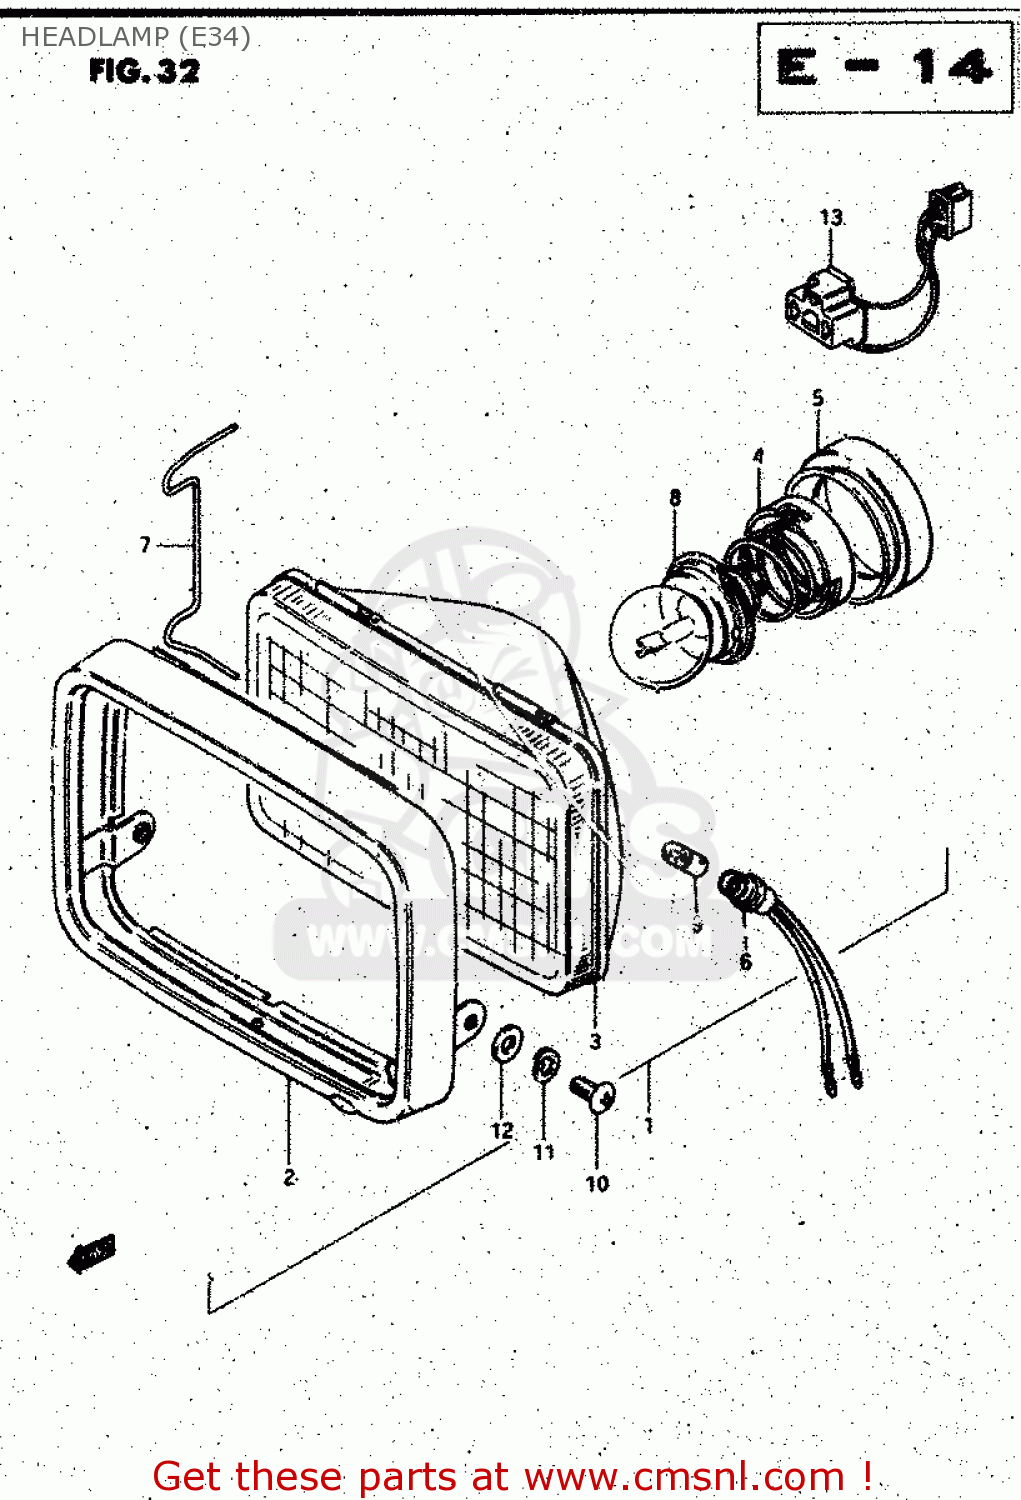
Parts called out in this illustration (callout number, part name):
1	HEADLAMP ASSY
2	RIM
3	UNIT
4	HOLDER,BULB
5	COVER, SOCKET
6	SOCKET,PARKING
7	SPRING
8	BULB(12V45/40W)
9	BULB(12V4W)
10	SCREW
11	LOCK WASHER
12	WASHER
13	LEAD WIRE, HEAD LAMP
